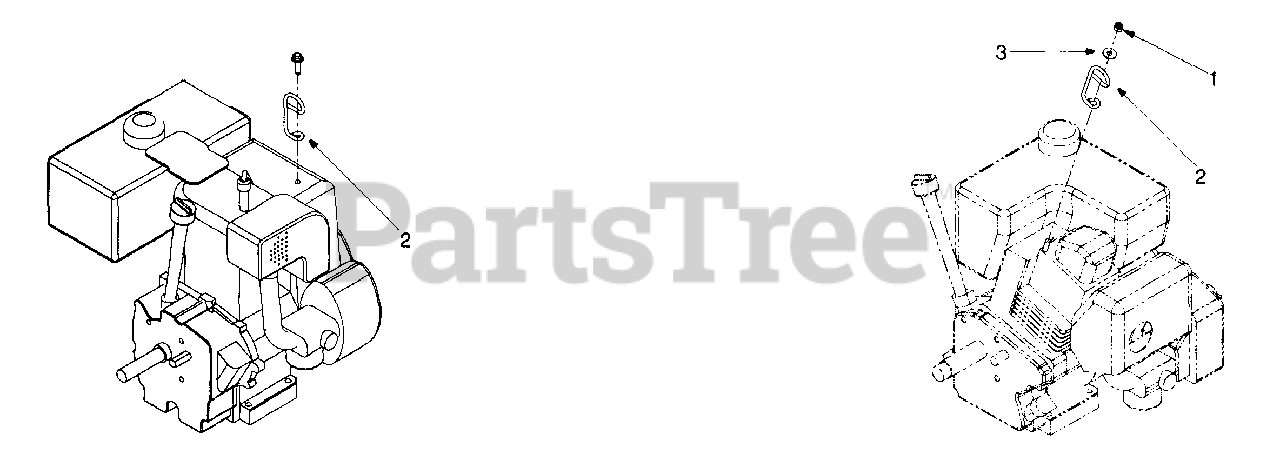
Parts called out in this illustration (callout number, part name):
1	Hex Lock Nut: 1/4-20
2	Cable Guide
3	Flat Washer
